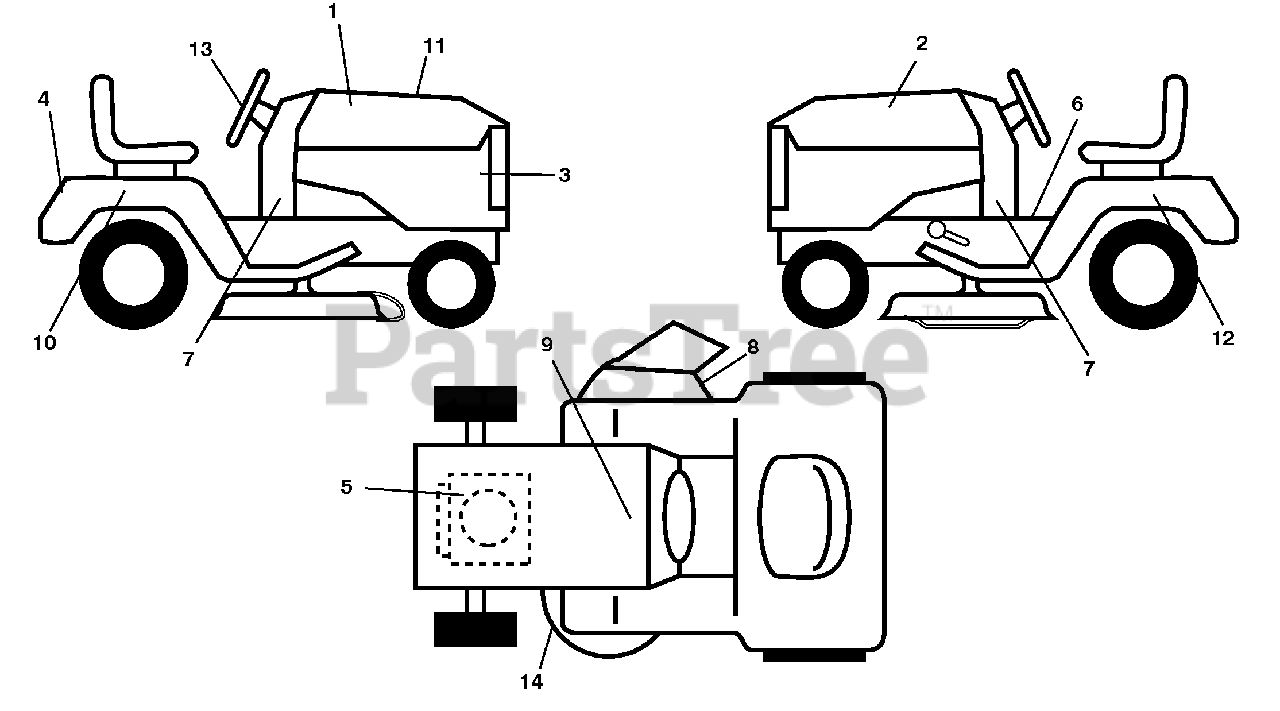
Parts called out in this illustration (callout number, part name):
1	Decal, Hood RH
2	Decal, Hood LH
3	Decal, Side Panel
4	Decal, Fender
5	Decal, Eng H.P.
6	Decal, Fender Operator's
7	Decal, Lower Dash
8	Decal, Warning
9	Decal, Battery Dnge/Poi
10	Decal, Fender SD RH
11	Decal, Replacement
12	Decal, Fender SD LH
13	Decal, Steering Wheel
14	Decal, Mower Schematic
14	Pad, Footrest Control
14	Decal, Bypass
14	Pad, Footrest, LH
14	Manual, Operator's (Eng/French)
14	Manual, Parts (Eng/French)
